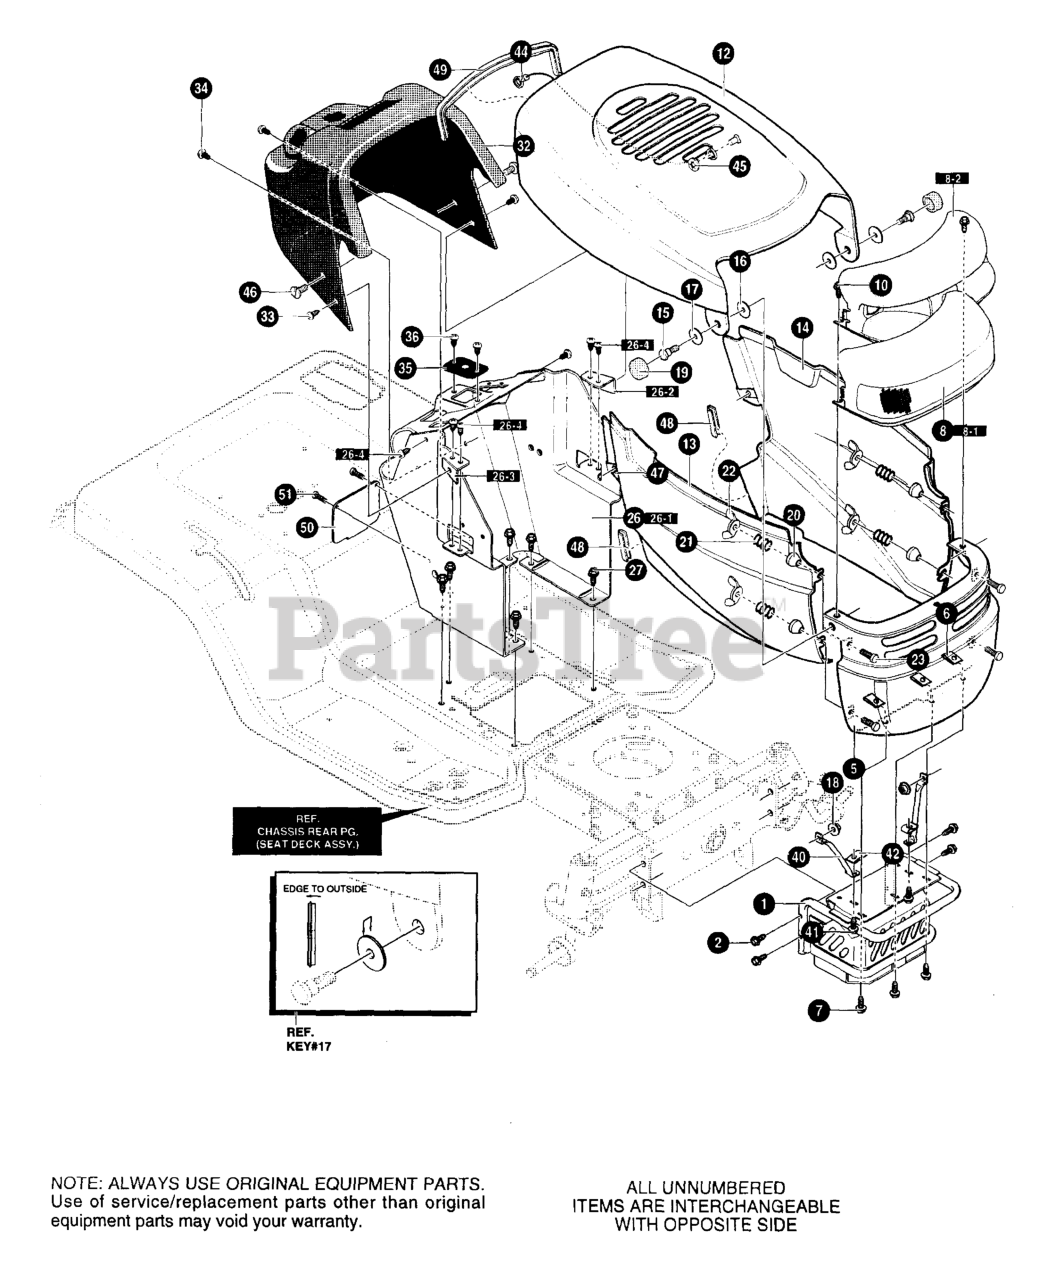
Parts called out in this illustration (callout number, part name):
1	WELD. ASM. COMMON BUMP/GRIL MNT
2	SCREW, 5/16-18 x 1.50 HHWATAP
6	NUT, "J" TINNERMAN #C702-1420Z
7	SCREW, 1/4-20X.63 HHWATAPSERBZ
8	ASM., LENS & REFLECTOR
8-2	REFLECTOR
10	SCREW, 1/4-14X.50 PANCR
12	ASSY., HOOD
13	PANEL, SIDE RH
14	PANEL, SIDE LH
15	BOLT, .497X.215 HHSH 3/8-16
16	WASHER, PLASTIC
17	PIVOT BASE
18	NUT, 3/8-16 HWDFLLK MACK 15X84
19	CAP, PIVOT
20	QUICK RELEASE-CAM
21	SPRING, COMP.500DX.5LG
22	NUT, WING 1/4-20 NYLON
23	SCREW, 1/4-20X1.25
26	CONSOLE ASSY
26-1	CONSOLE W/EXT HOLE HOME DEPOT
26-2	BRACKET, HOME DEPOT LH
26-3	BRACKET, HOME DEPOT RH
26-4	SCREW, 10-24X.500 SEGI
27	SCREW, 5/16-18 x 0.75 HHWATAP
32	DASH, BASIC HOME DEPOT
33	SCREW, 10-24X.500TRSEGI
34	SCREW, 10-24X.500TRSEGI
35	STEERING BRACKET
36	SCREW, 1/4-14X.50 PANCR
40	STRUT, GRILLE
41	SCREW, 1/4-20X.63-HHWATAP
42	SPEED NUT
44	LANYARD, HOOD
45	PUSHNUT
46	SCREW, 1/4-20X.63 PAPNHD
47	NUT, "J" TINNERMAN #C702-14202
48	TRIM (2 REQUIRED)
50	ACCESS, PANEL W/O SLOT
51	SCREW, 10-24X.500TRSEGI
